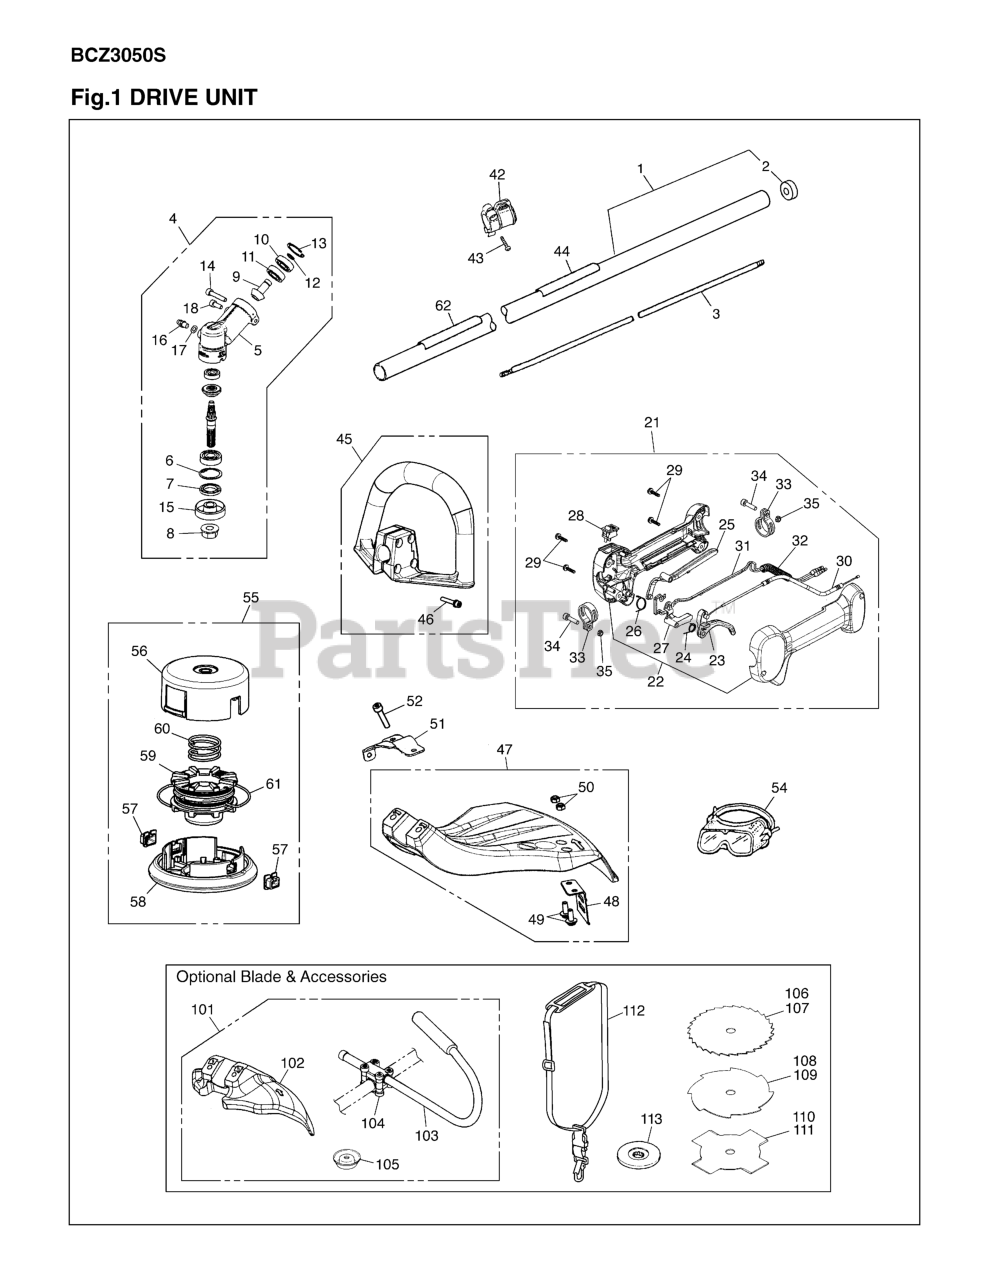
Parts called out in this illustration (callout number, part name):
1	PIPE COMP.
3	SHAFT (RPLS -122
4	GEARCASE ASSY
5	GEARCASE
6	RING,SNAP M26x1.
7	SEAL, OIL(RPLS 3
11	BEARING
12	SNAP RING
13	RING, SNAP, M24
14	BOLT, TORX
15	HOLDER (A)
16	FITTING, GREASE
17	WASHER, M6 x .8
18	BOLT, TORX
21	GRIP ASSY
22	GRIP, HALF SET
23	LEVER, THROTTLE
24	SPRING, THROTTLE
25	LEVER FOR GRIP (
27	LEVER JOINT
31	CORD - C
34	BOLT (RPLS 28501
35	NUT
42	HANGER COMP.
44	NAMEPLATE
45	HANDLE ASSY. (RP
47	GUARD ASSY
49	SCREW
52	BOLT, TORX
54	GOGGLExxx (RPLS
55	4
57	EYELET
58	COVER (RPLS T318
59	HOLDER, CORD (RP
61	CORD
62	LABEL CAUTON FOR
101	BLADE KIT
103	HANDLE, JACC.
104	BRACKET ASSY.
105	COVER(10mm)(RPL2
106	BLADE, 9
107	BLADE, 9
108	BLADE, 8
109	BLADE, 9
110	BLADE, 8
111	BLADE, 9
112	STRAP ASSY
113	HOLDER (B)
